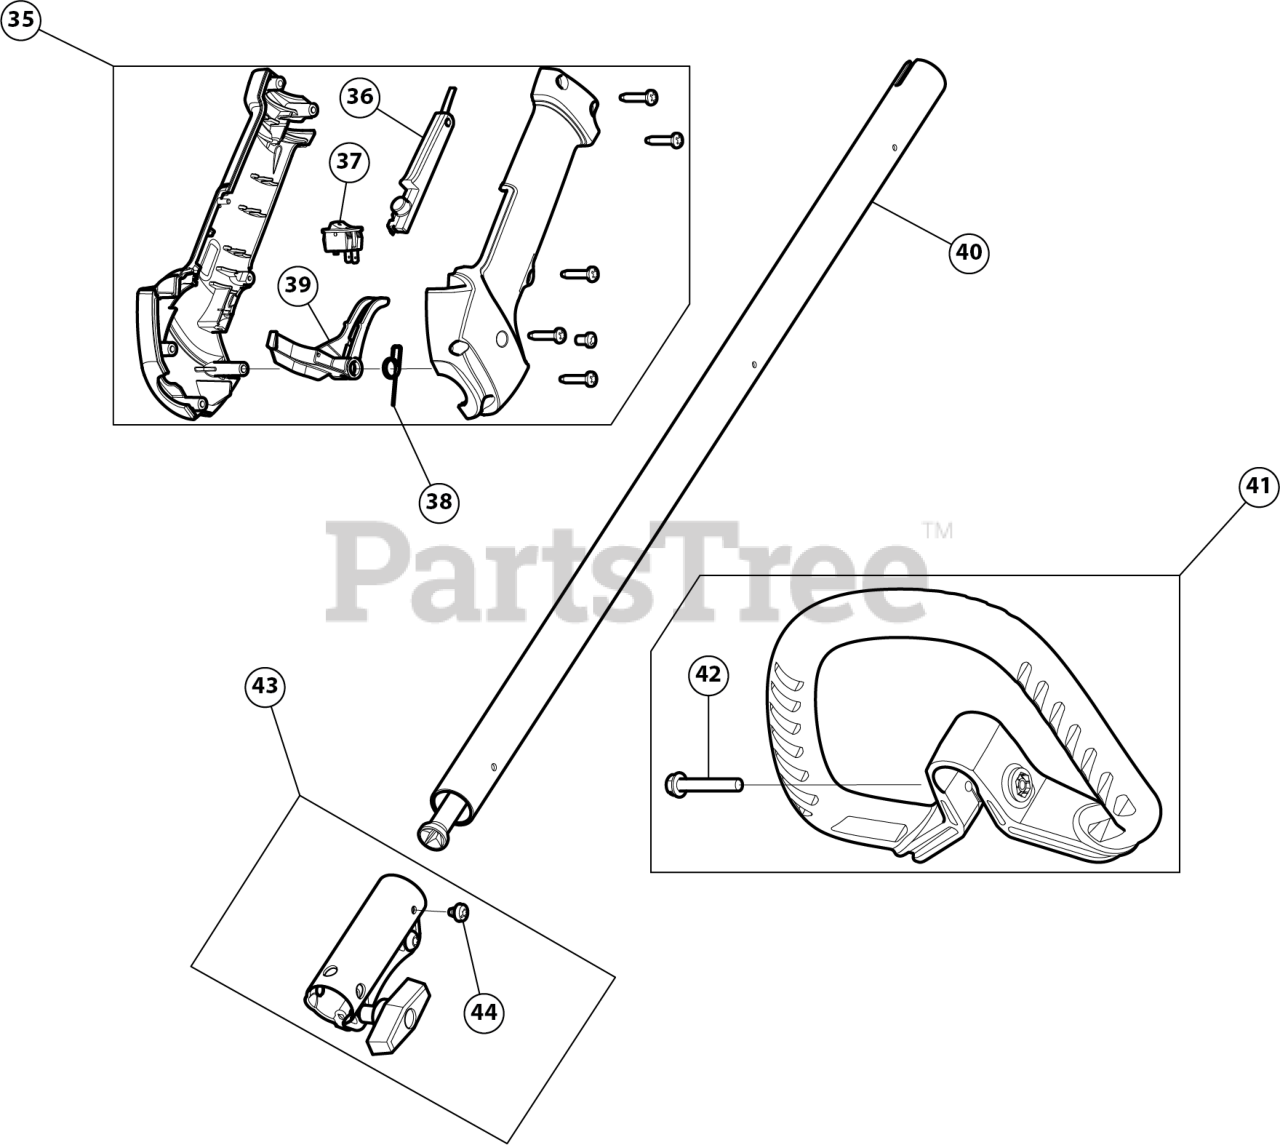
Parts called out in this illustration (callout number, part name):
35	THROTTLE GRIP ASSEMBLY
36	LEVER LOCK OUT
37	SW, MOMENTARY ON/O
38	TRIGGER SPRING
39	THROTTLE TRIGGER
40	BOOM ASSEMBLY UPR
41	HANDLE ASSEMBLY
42	BOLT 1/4-20X1 1/2
43	SPLIT BOOM COUPLER KIT
44	SCREW, 10-32X.250 TA
